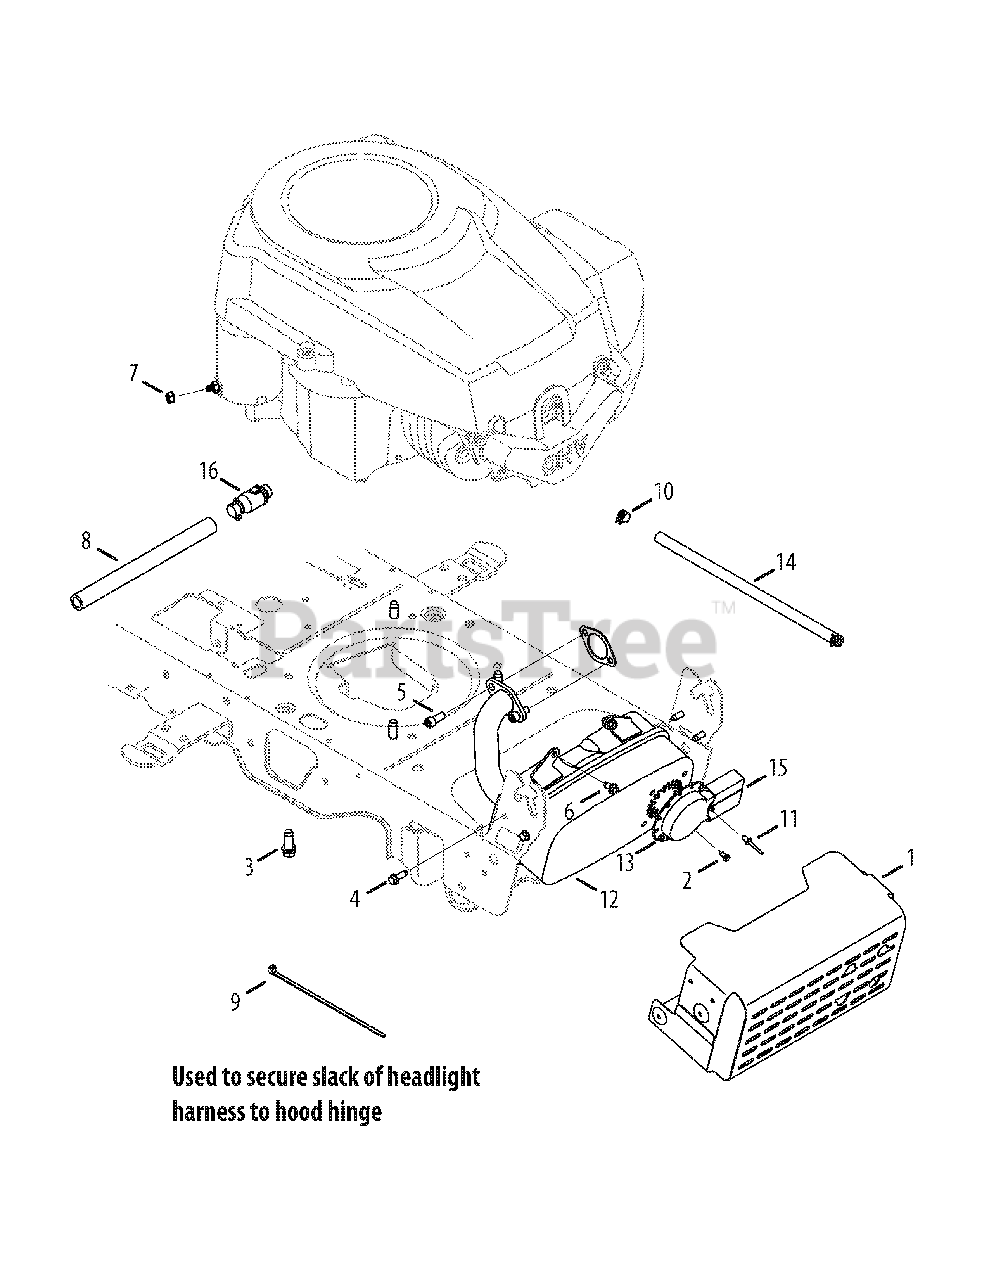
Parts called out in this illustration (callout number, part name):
1	Muffler Shield Assembly
2	Screw, Indented Washer, #8-18:0.500
3	Taptite Screw, 3/8-16:1.000
4	Taptite Screw, 1/4-20:0.500
5	Socket Head Screw, 5/16-18:.750
6	Taptite Screw, 1/4-20 x .625
7	Sems Nut, 1/4-20
8	Extension Hose, Oil Drain
9	Cable Tie, 3/16 x .05 x 7.4
10	Hose Clamp, .490 DIA.
11	Rivet, .188 DIA x .300 L
12	Muffler
13	Muffler Deflector
14	Fuel Hose
15	Long Muffler Deflector
16	Oil Drain
